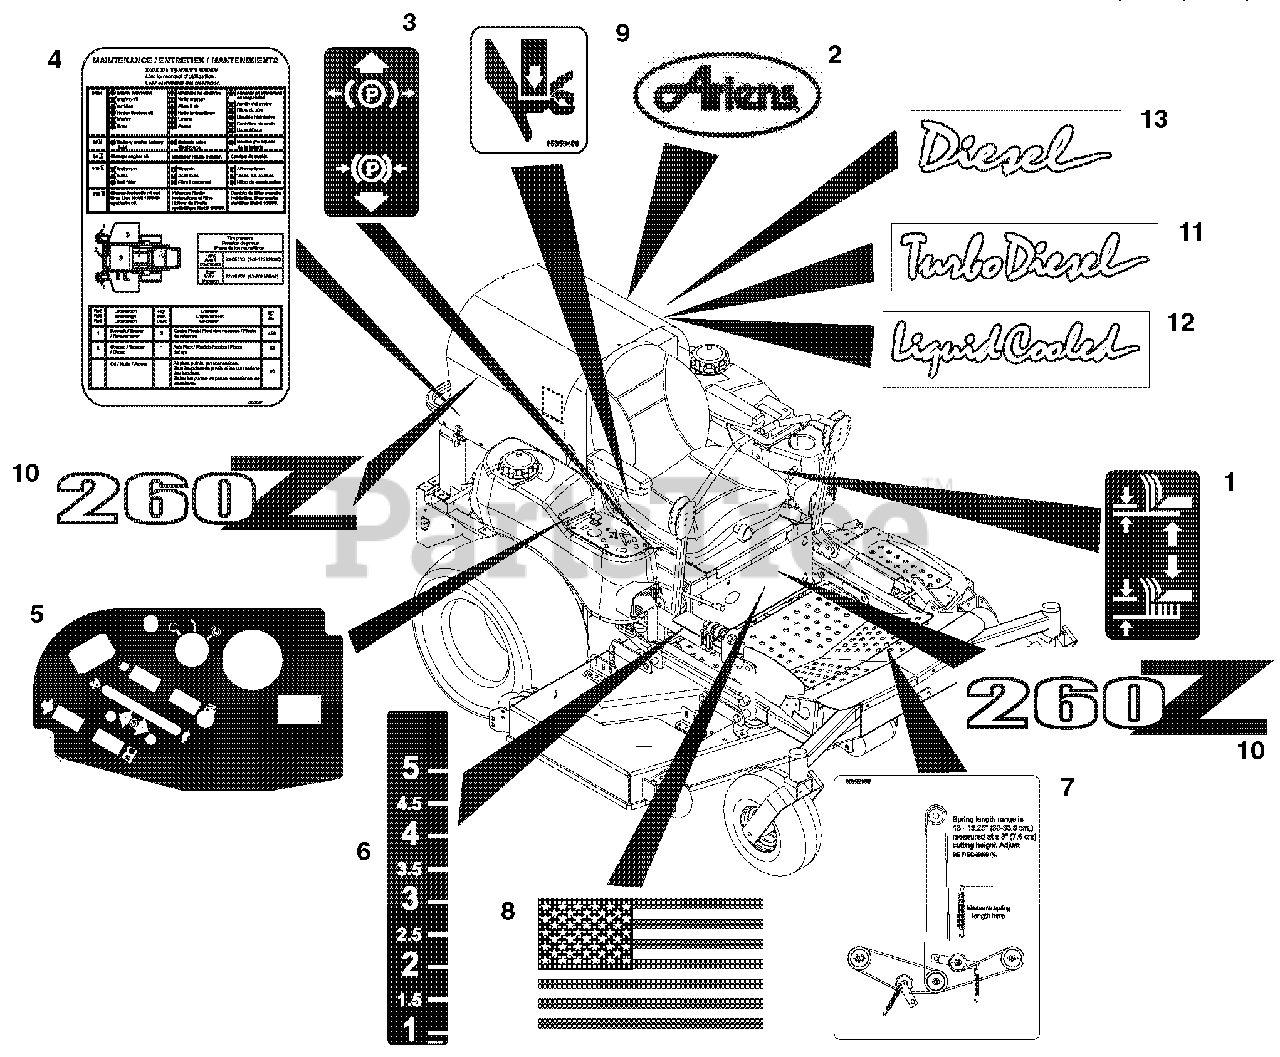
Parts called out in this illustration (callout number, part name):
1	Decal, Lift Lever
2	Decal, Ariens
3	Decal, Parking Brake Lever
4	Decal, Maintenance Instructions
5	Decal, Control Panel
6	Decal, Height of Cut
7	Decal, Belt Diagram
8	Decal, American Flag
9	Decal, Pinch Point
10	Decal, PM260Z (316, 317)
11	Decal, Turbo Diesel (317, 321)
12	Decal, Liquid Cooled
13	Decal, Diesel (316, 322)
